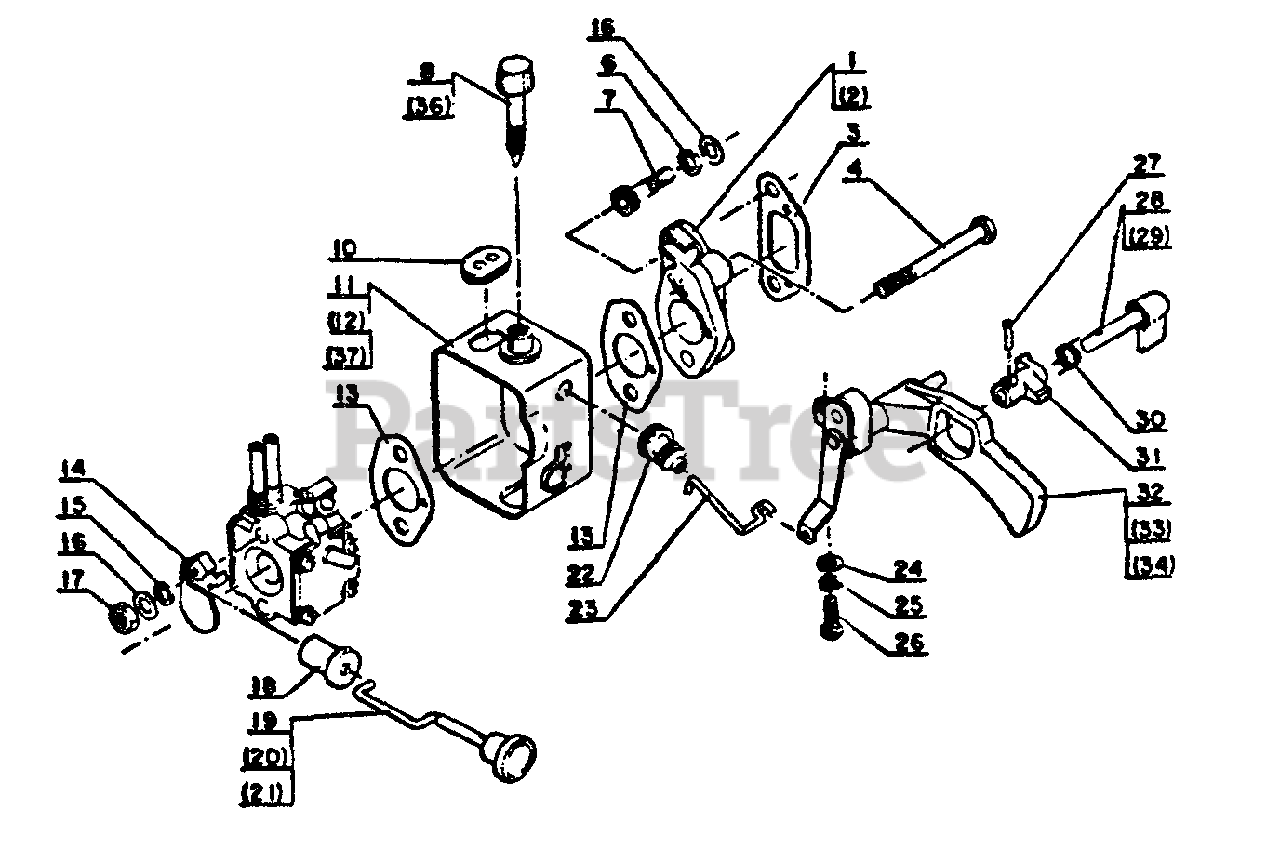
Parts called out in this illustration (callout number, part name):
1	CASE, CARBURETOR
3	GASKET, INTAKE
5	WASHER - 5
6	LOCKWASHER - 5
7	BOLT - 5X20
8	SCREW, IDLE ADJUST
10	GROMMET
11	CASE, CARBURETOR
13	GASKET, INTAKE
14	SHUTTER, CHOKE
15	WASHER - 5
16	WASHER - 5
17	LOCKNUT - 5
18	GROMMET
19	ROD, CHOKE
22	GROMMET
23	ROD, THROTTLE
24	WASHER - 4
25	LOCKWASHER - 4
26	SCREW - 4X14
27	PIN - SPRING
28	LEVER, THROTTLE
30	SPRING, LOCKOUT LEVER
31	LOCKOUT, THROTTLE
32	TRIGGER, THROTTLE
